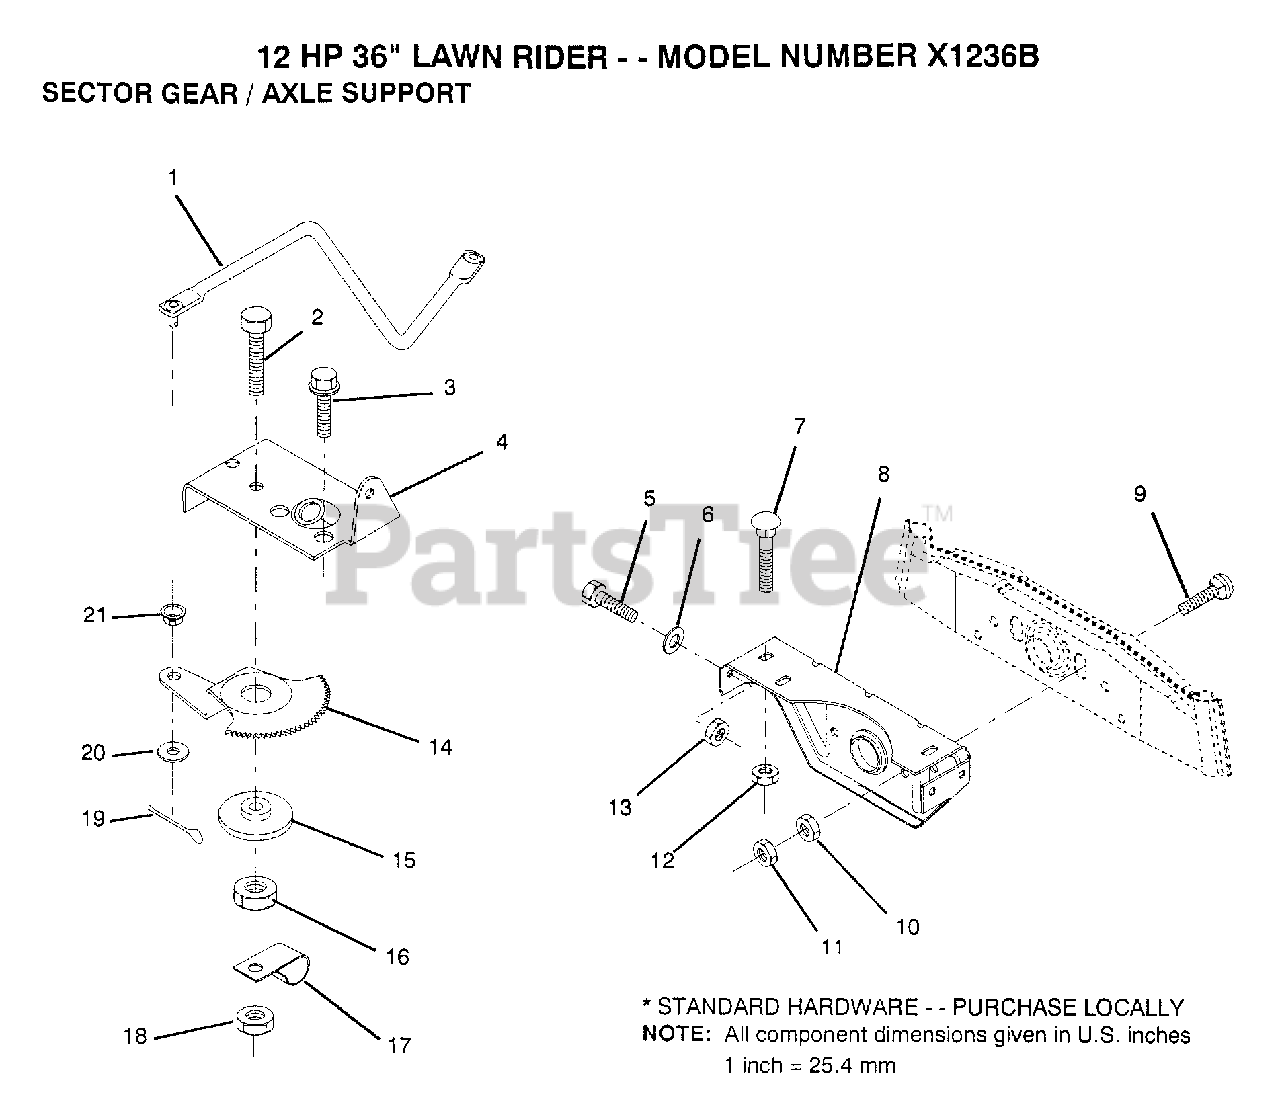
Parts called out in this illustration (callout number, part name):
2	"BOLT,HEX"
3	SCREW LT
4	"PLATE,STR SUPT"
5	BOLT
6	WASHER
7	BOLT
8	"SUPT,FRT AXLE"
9	BOLT
10	NUT.HEX.3/8-16UNC
11	LOCKNUT
14	GEAR SECTOR
15	BUSHING
16	NUT
17	CLIP INSULATOR
18	NUT LTV
19	COTTER PIN
20	WASHER
21	BUSHING.DRAGLINK
